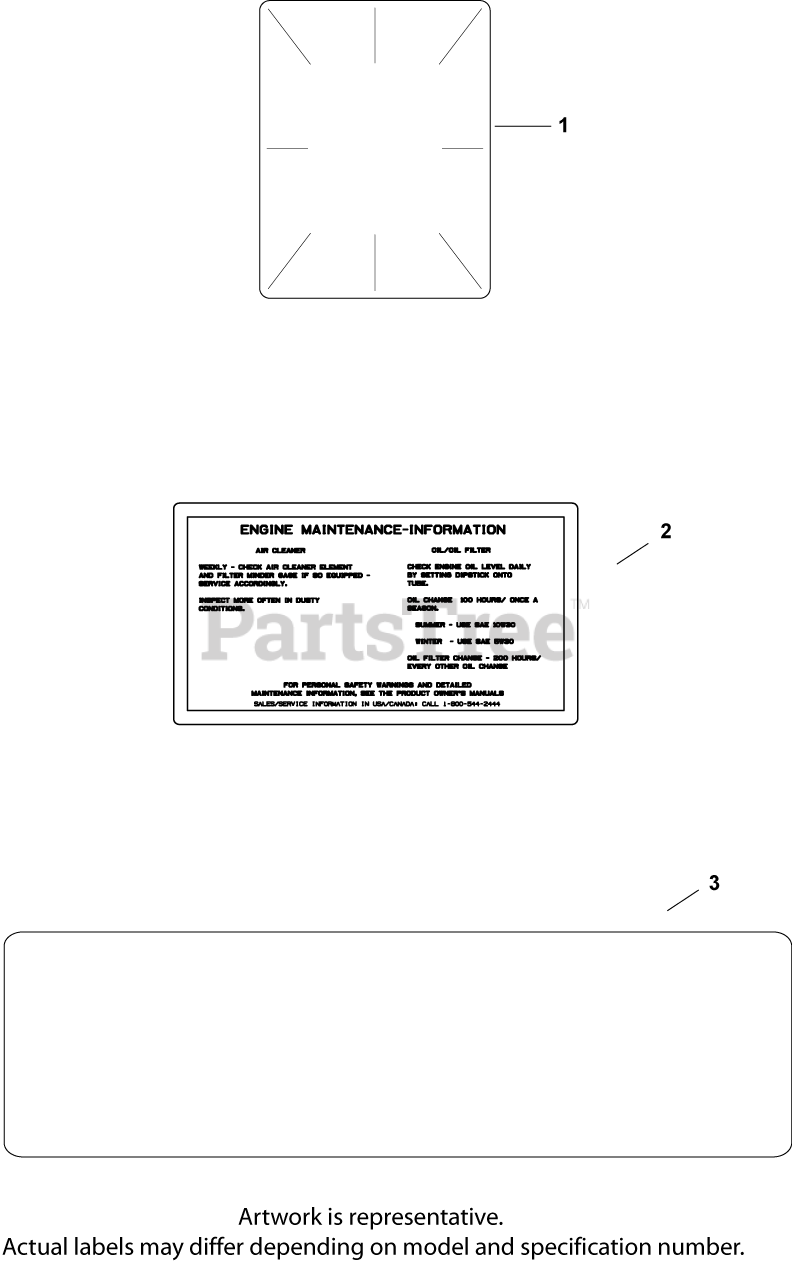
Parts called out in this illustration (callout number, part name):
1	DECAL, 23 HP
2	DECAL, AIR CLEANER - (#DSC)
3	DECAL, CLEAR LAMINATE USE 25 113 70-S
